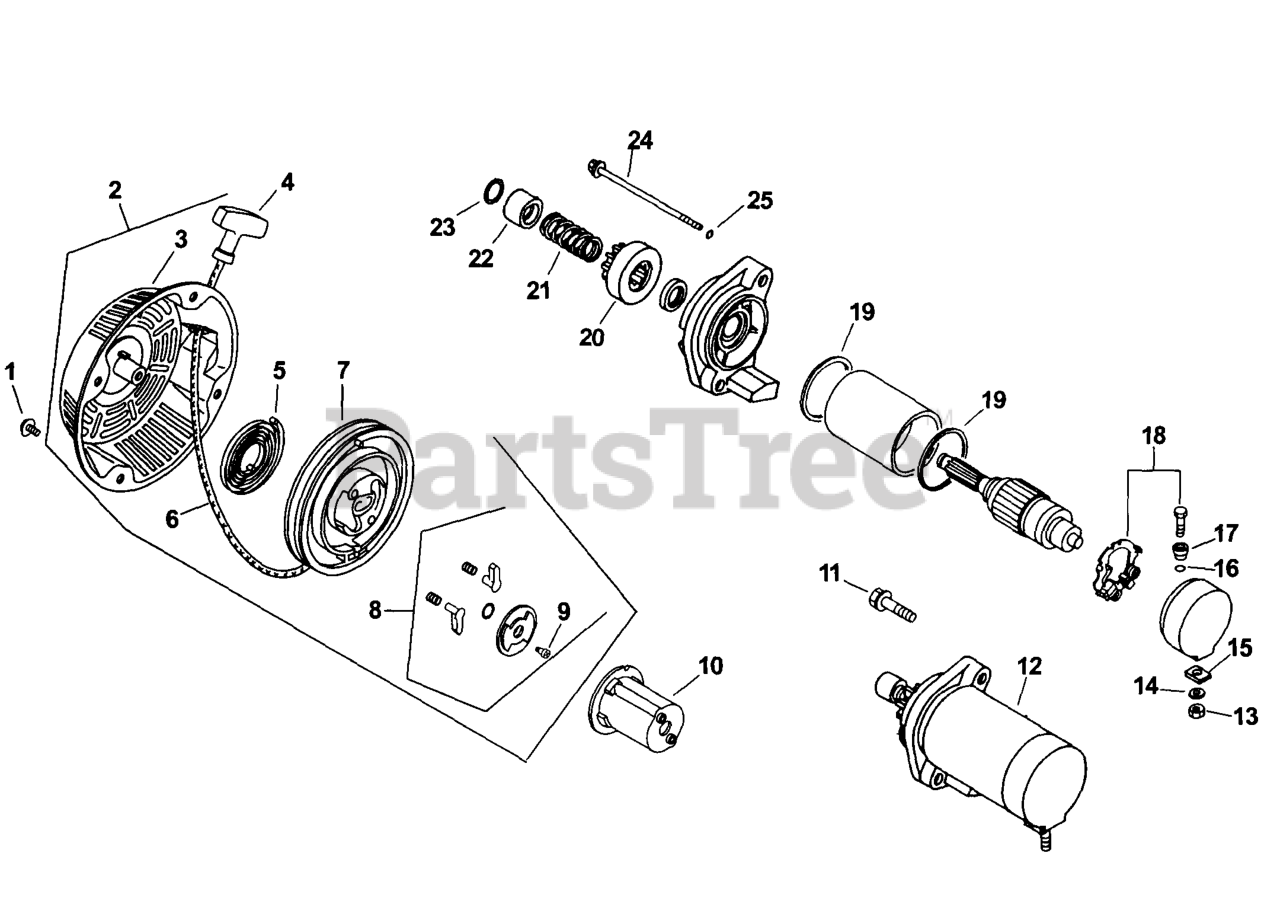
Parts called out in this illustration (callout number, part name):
2	RETRACTABLE STARTER
3	HOUSING ASSEMBLY
5	SPRING, STARTER
6	ROPE, STARTING
8	KIT,PAWL REPAIR - CS8.5,10,12
10	CUP, DRIVE
